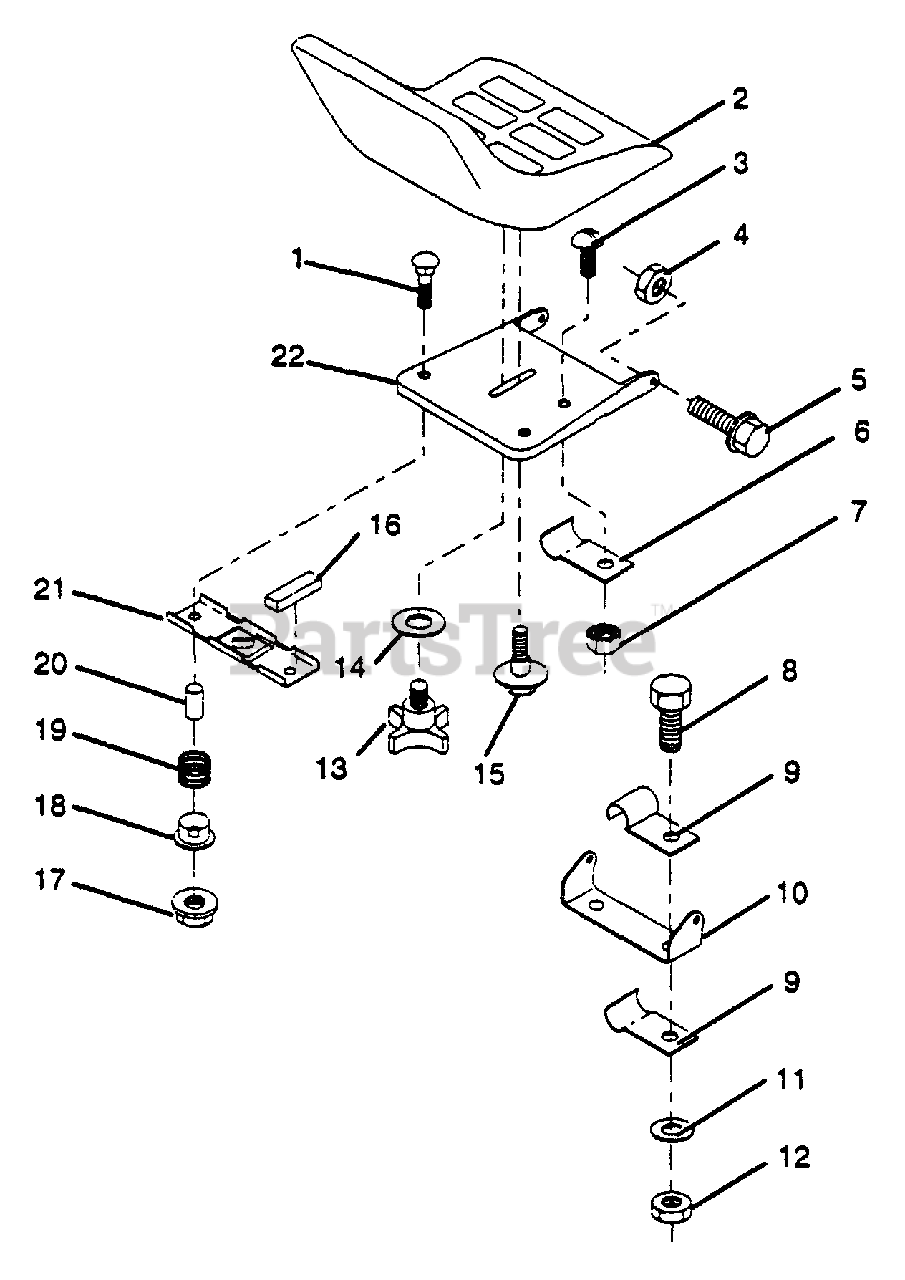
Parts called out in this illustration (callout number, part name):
1	Bolt, Carriage 1/4-20 x 1-1/4
2	Seat
3	Screw, Slotted Pan Head #10-32 x 1/2
4	Nut, Crownlock 5/16-18
5	Bolt, Shoulder 5/16-18 UNC
6	Clip, Insulated
7	Nut, Keps # 10-32 UNF
8	Bolt, Fin. Hex 3/8-16 UNC x 3/4
9	Clip, Insulated
10	Bracket, Pivot Seat
11	Washer 13/32 x 3/4 x 10 Ga.
12	Nut, Crownlock 3/8-16 UNC
13	Knob 1/2" Seat
14	Washer, 17/32 x 1- 3/16 x 12 Ga.
15	Bolt, Shoulder
16	Strip, Foam
17	Nut, Hex Large Flange Lock
18	Bushing, Snap
19	Spring, Compression
20	Spacer, Split 28 Id. x .88 Lg.
21	Bracket, Switch, Mounting
